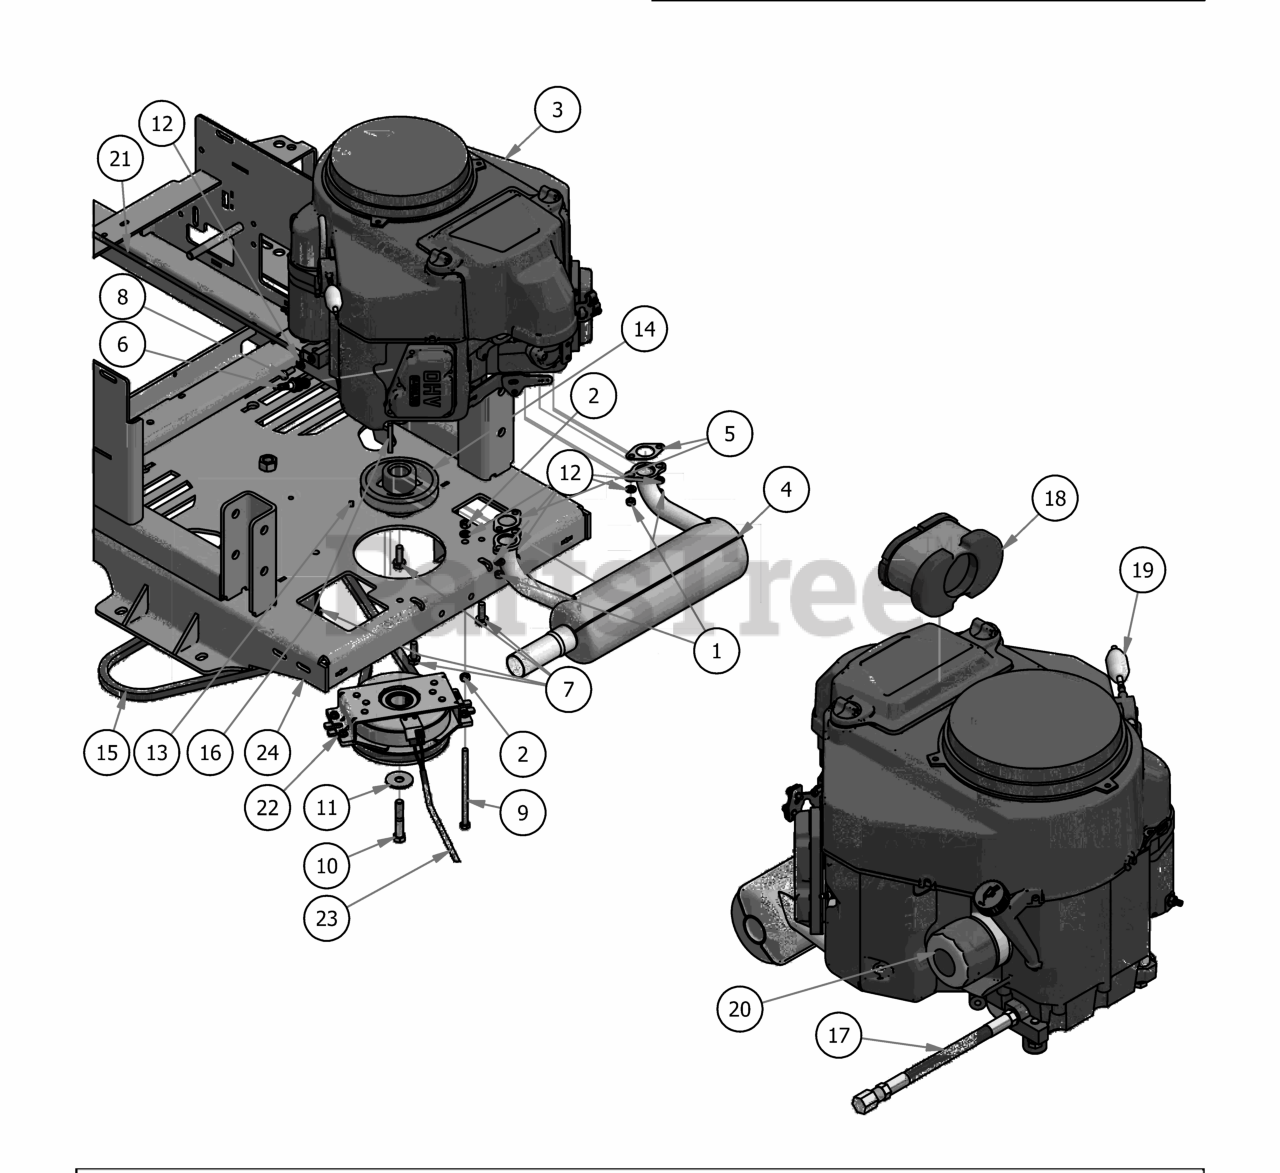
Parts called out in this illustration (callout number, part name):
1	M8-1.25 Zinc Nut
3	FS730V Engine
4	Kawasaki Muffler 1251
5	Exhaust Gasket
6	Spark Plug - Kawasaki
7	3/8 x 1 1/8 bolt
8	M8x1.20x20MM Hex head bolt
9	5/16-18 x 5-1/2 GR 5 Hex Bolt
10	7/16"-20 x 2.5" Hex Bolt Gr. 8
11	1/2" Belleville Washer
12	5/16" Lock Washer
13	5/16 Set Screw
14	4 3/4 Motor Pulley
15	75.8" Pump Belt
16	1/4 x 2 Square key Stock
17	Oil drain Hose
18	Kawasaki Air Filter
19	Universal Inline Fuel Filter
20	Kawasaki Oil Filter
21	24" Black Ground Cable
23	Clutch Pigtail
24	2018 Maverick Frame
